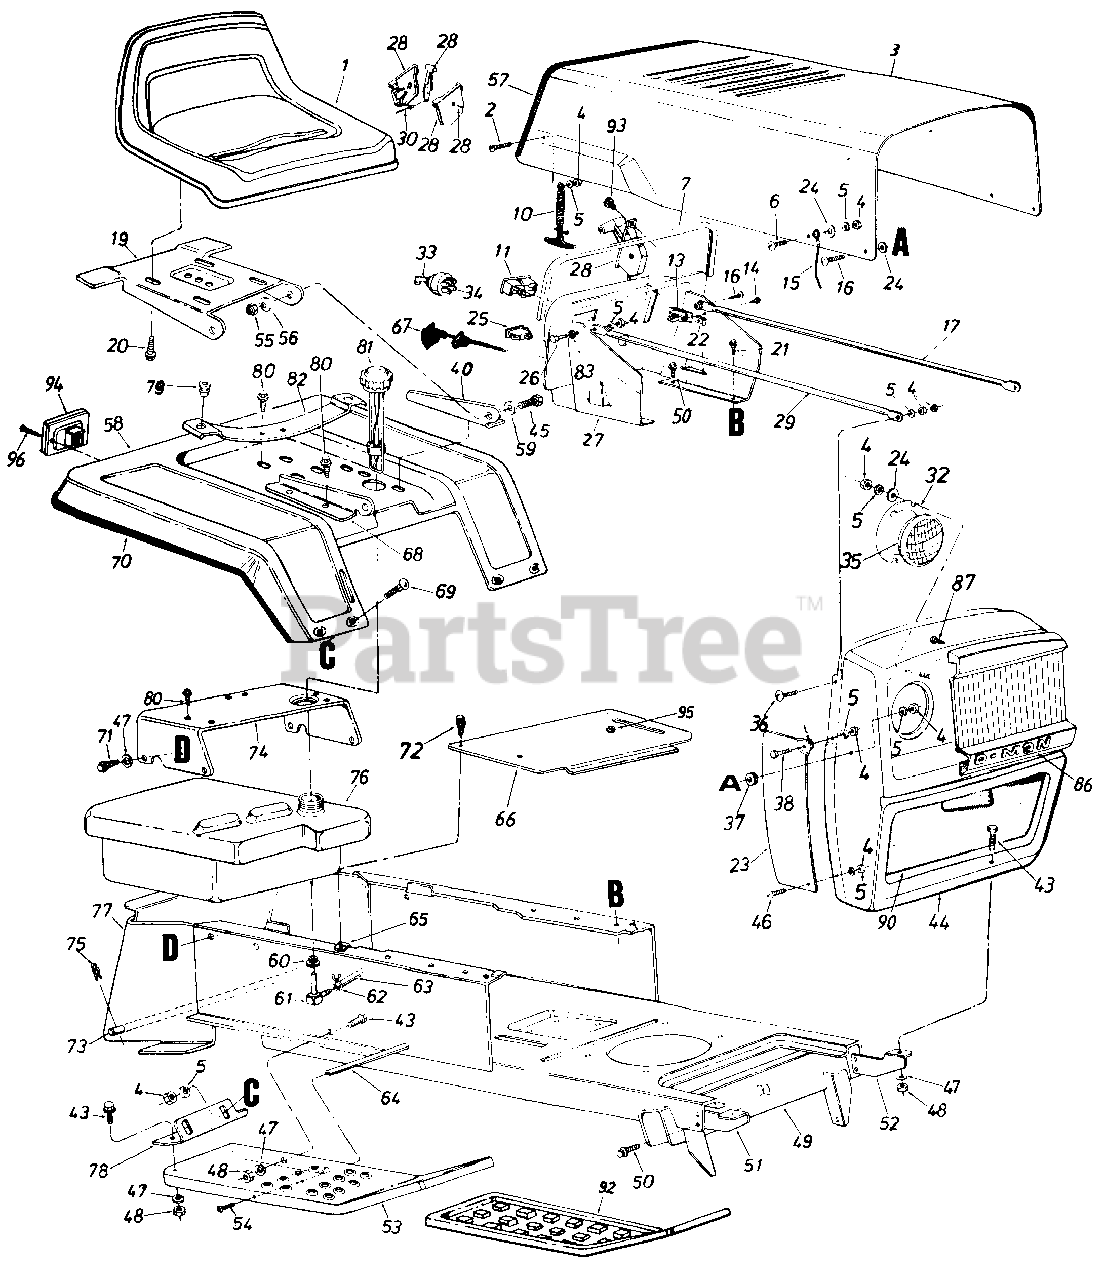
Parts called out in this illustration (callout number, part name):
1	Seat Assembly
2	Truss Mach. Scr. 1/4-20 x .50" Lg.
5	L-Wash. 1/4" Scr.
6	Truss Mach. Scr. 1/4-20 x .50" Lg.
7	Vinyl Molding Strip 29"
10	Hood Latch Ass'y.
11	Ammeter
13	Circuit Breaker 8 Amp.
14	Hex Tap Scr. #10 x .50" Lg.
15	Hood Stop
16	Truss Mach. Scr. 1/4-20 x .75" Lg.
17	Grille Positioning Rod
19	Seat Pivot Brkt.
20	Hex Wash. Hd. AB-Tap Scr. 3/8 x .75" Lg.
21	Hex Thd. Rolling Scr. 1/4" x .50" Lg.
22	Speed Nut #10Z
23	Grille Side Panel R.H.
24	Fl-Wash. 1/4" I.D.
25	Light Switch
26	Truss Hd. Scr. 1/4-20 x 1.00" Lg.
27	Dash Panel Ass'y.
28	Throttle Control Box Comp.
29	Grille Positioning Rod
30	Throttle Control Cable
32	Head Lamp Retainer
33	Ignition Key
34	Ignition Switch
35	Head Lamp
36	Truss Machine Scr. 1/4-20 x .75" Lg.
37	Rubber Wash. .50" I.D. x 1.00 O.D. x .25 Thk.
38	Truss Mach. Scr. 1/4-20 x .5"
40	Seat Bracket L.H.
43	Hex Scr. 5/16-18 x .75" Lg.
44	Grille Ass'y.
45	Hex Bolt 5/16-18 x .75" Lg.
46	Truss Mach. Scr. 1/4-20 x .5"
47	L-Wash. 5/16" I.D.
48	Hex Nut 5/16-18 Thd.
49	Lower Frame Ass'y.
50	Hex Thd. Rolling Scr. 5/16" x.75" Lg.
51	Grille Mount Brkt. R.H.
52	Grille Mount Brkt. L.H.
53	Running Board R.H.
54	Truss Mach. Scr. 5/16-18 x .75" Lg.
55	Hex Cent. L-Nut 5/16-18 Thd.
56	Bell-Wash. .34" I.D. x .88 O.D.
57	Vinyl Moulding Strip 30"
58	Fender Ass'y.
59	Bell-Wash. .34" I.D. x .88" O.D.
60	Bushing
61	90ø Nipple
62	Hose Clamp 3/8"
63	Gas Line 46" Lg.
64	Running Board Rod
65	Speed Nut #10-24
66	Transmission Cover Ass'y.
67	Choke Control Comp.
68	Seat Bracket R.H.
69	Carr. Bolt 1/4-20 x .50" Lg.
70	Trim Strip 81" Lg.
71	Hex Thd. Rolling Scr. 5/16-24 x .75" Lg.
72	Truss Hd. Scr. #10 x .50" Lg.
73	Hitch Rod
74	Seat Mounting Channel
75	Internal Cotter Pin
76	Gas Tank
77	Hitch Plate
80	Hex Wash. Hd. Self-Tap Scr. 5/16-18 x .50" Lg.
81	Gas Gauge
82	Seat Spring
83	External Wash. 1/4" I.D.
86	Headlight Bezel
87	Self-Tap Scr. #8 x .5" Lg.
90	Grille Screen
92	Foot Pad
93	Truss Mach. AB-Tap Scr. #1 0 x .50" Lg.
94	Taillight
95	Snap Bushing
96	Truss AB-Tap Scr. #6 x .62" Lg.
